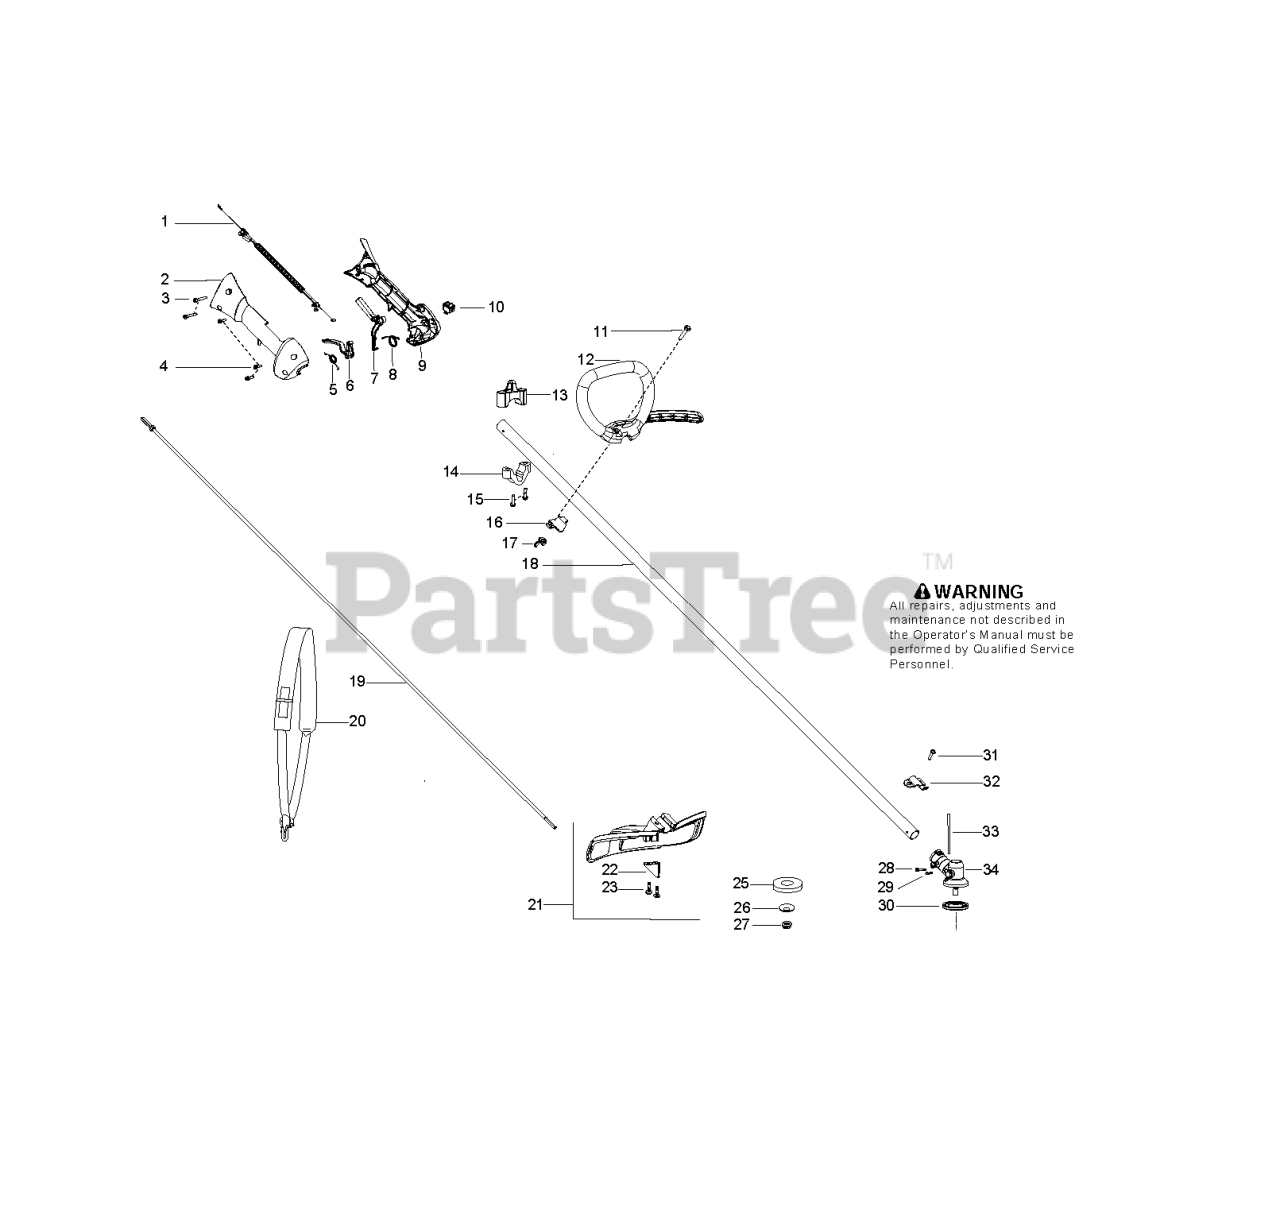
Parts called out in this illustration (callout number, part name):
1	ASSY-CABLE WIRE HARNESS
2	HOUSING-THROTTLE RH
4	SCREW M4 X 1.75 PT 16MM
5	SPRING TRIGGER
6	TRIGGER THROTTLE
7	THROTTLE LOCKOUT
8	SPRING LOCKOUT
9	HSG THROTTLE LH
10	KIT SWITCH
11	BOLT, TYPE 2
12	ASSY HANDLE JBAR
13	CLAMP HARNESS UPPER
14	CLAMP HARNESS LOWER
16	CLAMP ASSIST HANDLE
17	WINGNUT, TYPE 2
18	DRIVE SHAFT ASSY
20	Harness-w/o warning
21	KIT COBI SHIELD
22	Limiter - Line
25	SUPPORTING CUP
26	SUPPORT FLANGE
27	GEARHEAD NUT - BRUSHCUTTER
28	SCREW - CARB. ADAPTOR
30	DRIVE DISC
31	SCREW 1/4-20 X 7/8 (TAP
32	BRACKET SHIELD STRAIGHT SHAFT
33	LOCKING PIN
34	ASSY GEARBOX
